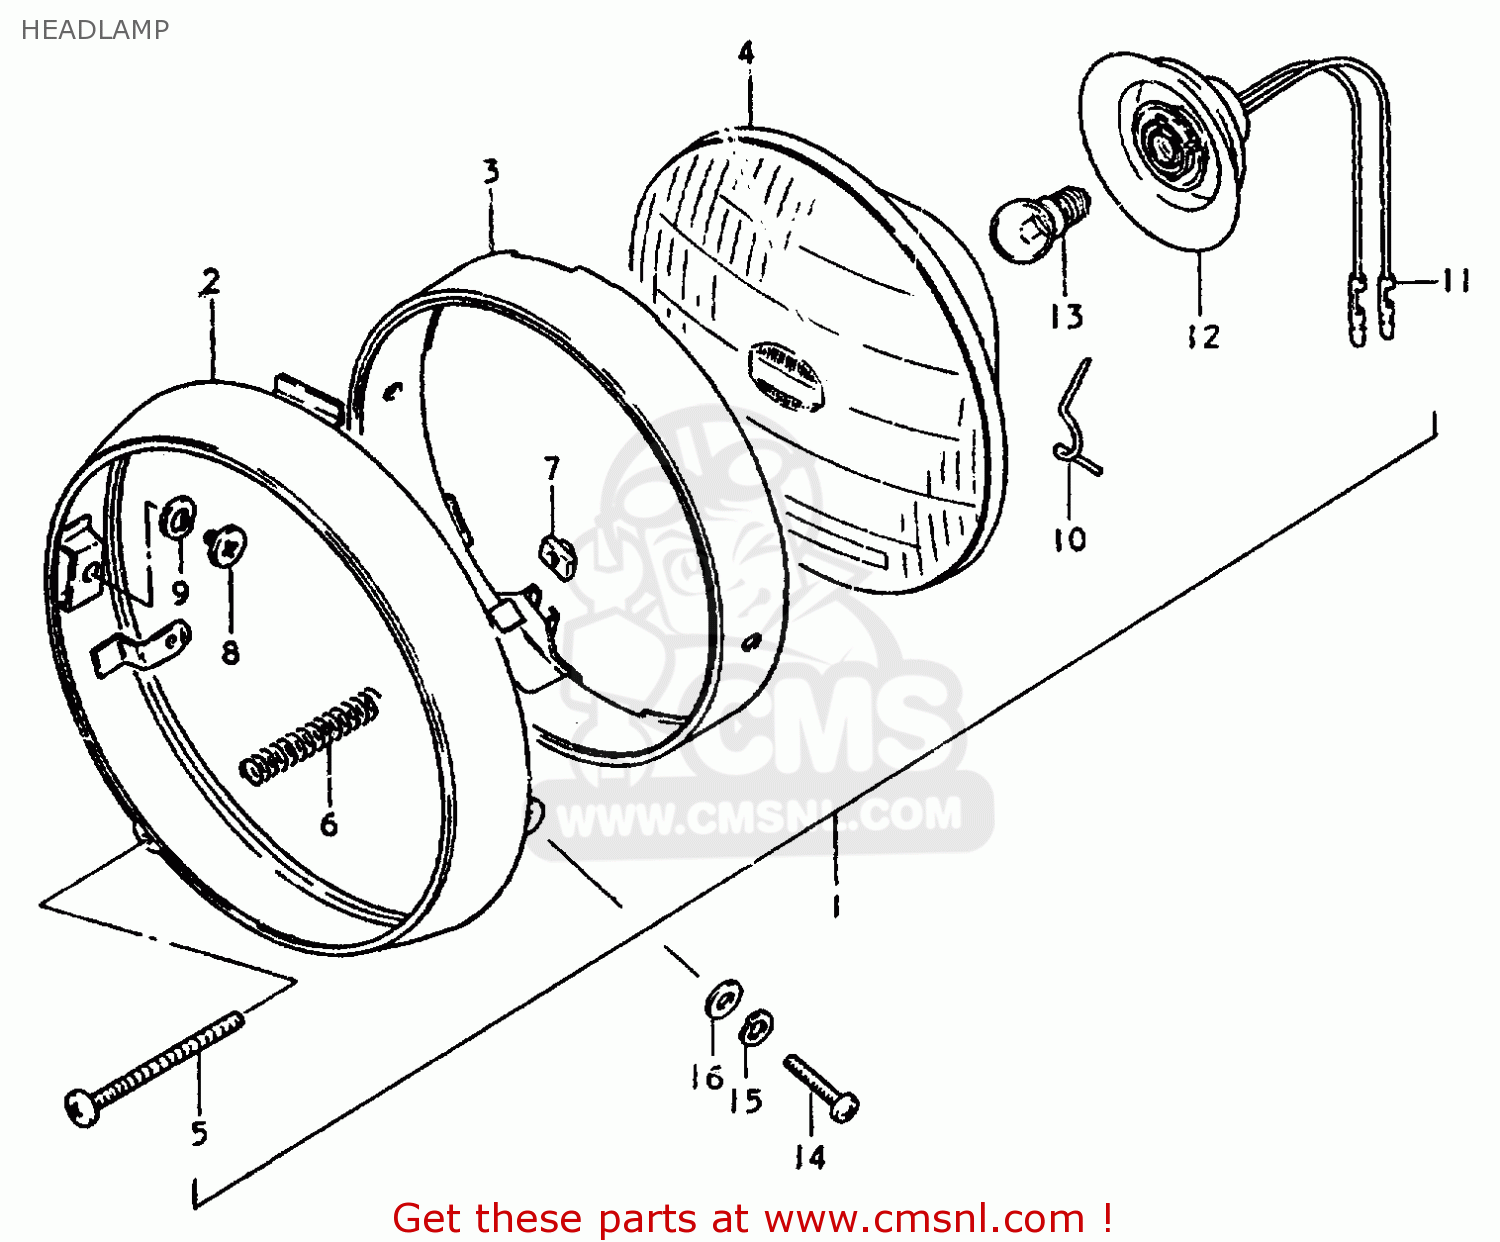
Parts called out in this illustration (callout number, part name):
1	HEADLAMP ASSY
2	RIM
3	RETAINER
4	UNIT
5	SCREW,HEADLAMP ADJUST
6	SPRING,ADJUSTING
7	NUT
8	SCREW
9	LOCK WASHER
10	SPRING
11	SOCKET
12	COVER
13	BOLT (6V,6W)
14	SCREW
15	LOCK WASHER
16	WASHER
